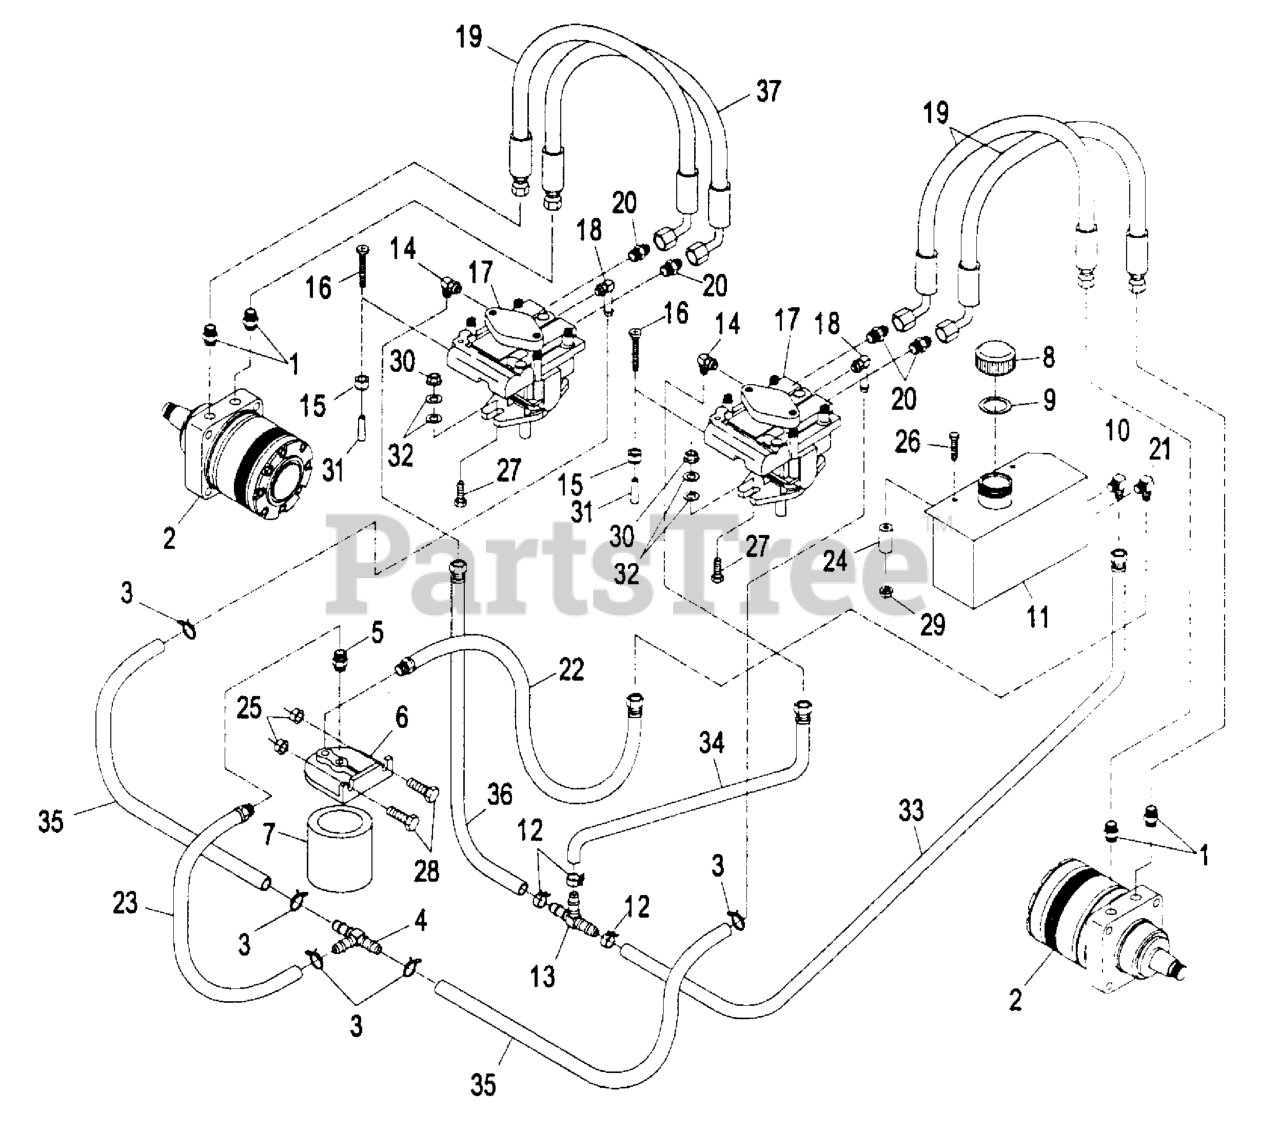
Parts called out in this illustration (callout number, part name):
1	FITTING-STRAIGHT
2	HYD MOTOR ASM
3	CLAMP-HOSE
4	FITTING-TEE, HOSE
5	FITTING-STRAIGHT
9	GASKET-CAP, TANK
10	FITTING-ELBOW
12	CLAMP-HOSE
13	FITTING-TEE, HOSE
14	FITTING-90 DEG
18	FITTING
20	FITTING-STRAIGHT
21	FITTING-ELBOW
22	ASM,HOSE LO PRESSURE
23	ASM,HOSE CHARGE LINE
31	GRIP-VALVE, DUMP
33	ASM,HOSE CASE DRAIN
34	HOSE ASM
36	HOSE ASM
37	HOSE-PRESSURE, HIGH
